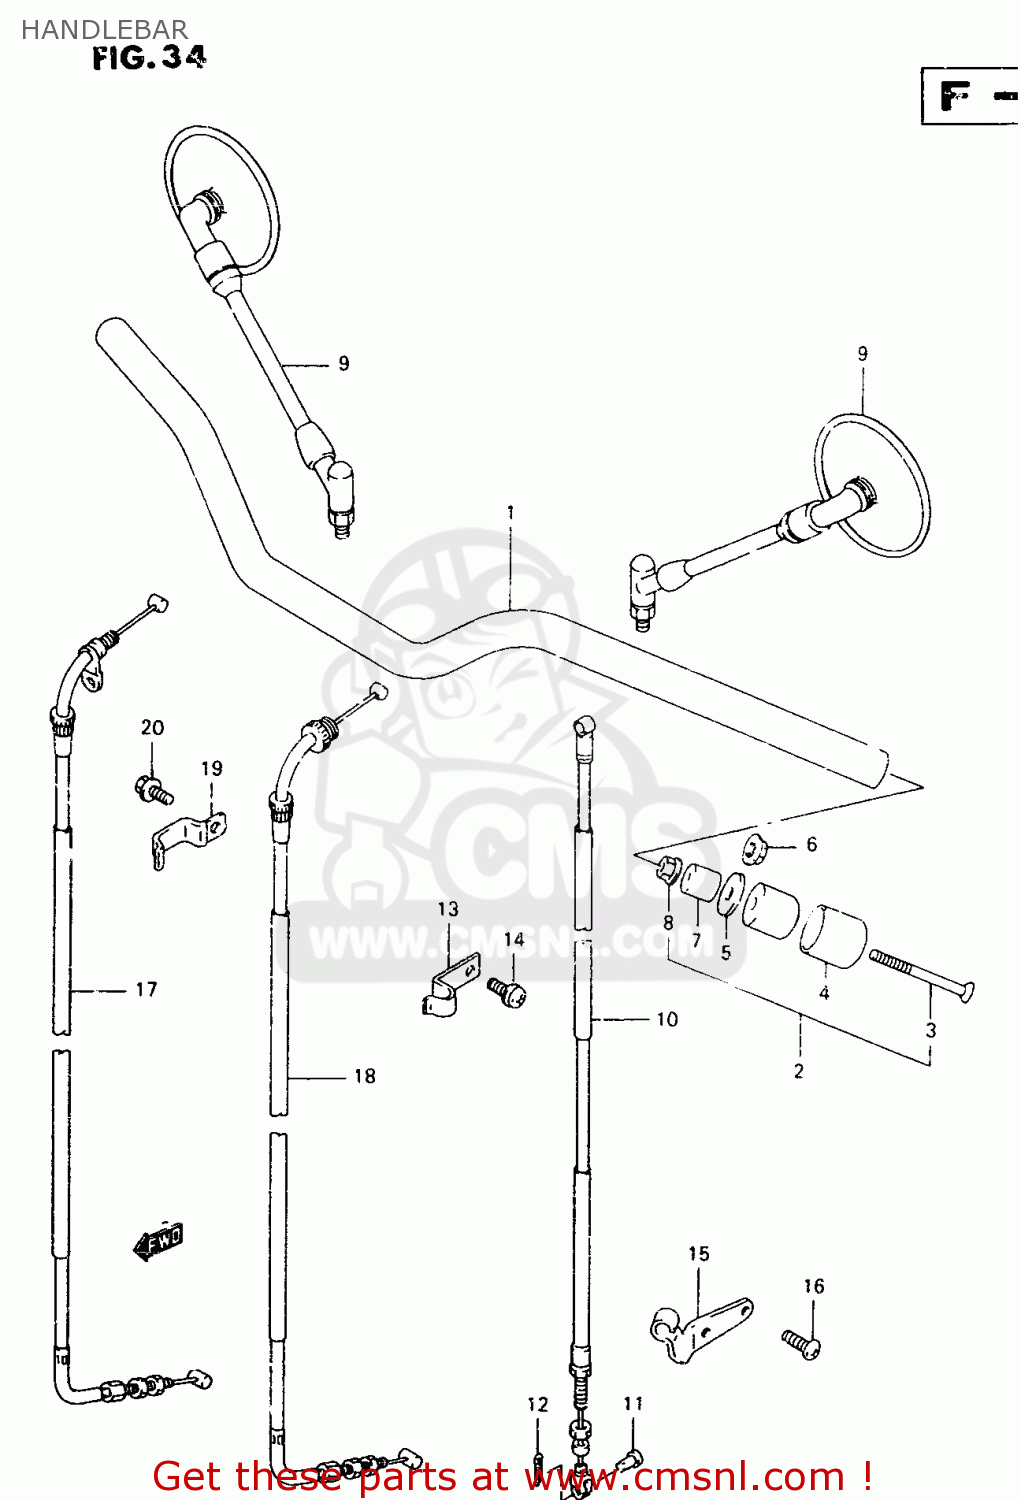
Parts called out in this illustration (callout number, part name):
1	HANDLEBAR
2	BALANCERSET,H/
3	SCREW
4	CAP,BALANCER
5	SPACER,BALANCER
6	NUT
7	EXPANDER,HANDLE BALANCER
8	NUT
9	MIRROR ASSY,RH
10	CABLE ASSY,CLUTCH
11	PIN(L:13)
12	PIN
13	CLAMP,CLUTCH CABLE NO.1
14	SCREW
15	STOPPER,CLUTCH CABLE
16	SCREW
17	CABLE ASSY,THROTTLE NO.1
18	CABLE ASSY,THROTTLE NO.2
19	CLAMP
20	BOLT
